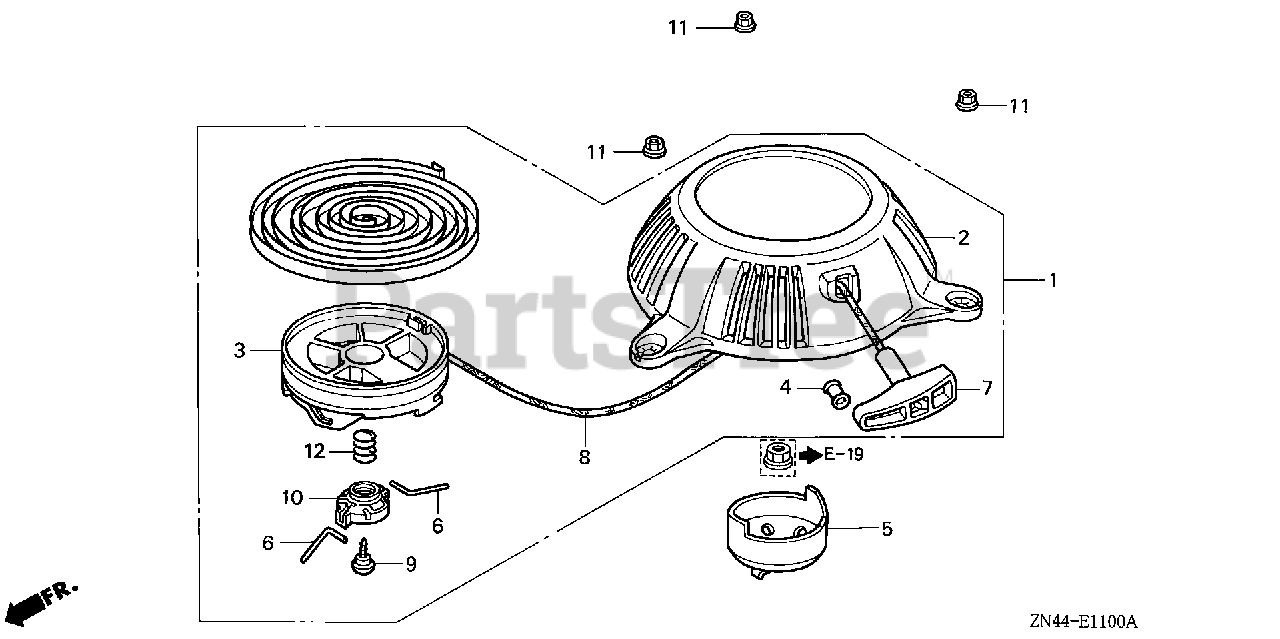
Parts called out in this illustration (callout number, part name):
1	STARTER ASSY., RECOIL
2	CASE, RECOIL STARTER
3	REEL, RECOIL STARTER
4	GUIDE, ROPE
5	PULLEY, RECOIL STARTER
6	SWINGARM
7	KNOB, RECOIL STARTER
8	ROPE, RECOIL STARTER
9	SCREW, SETTING
10	COLLAR
11	NUT, FLANGE (5MM)
12	SPRING, FRICTION
